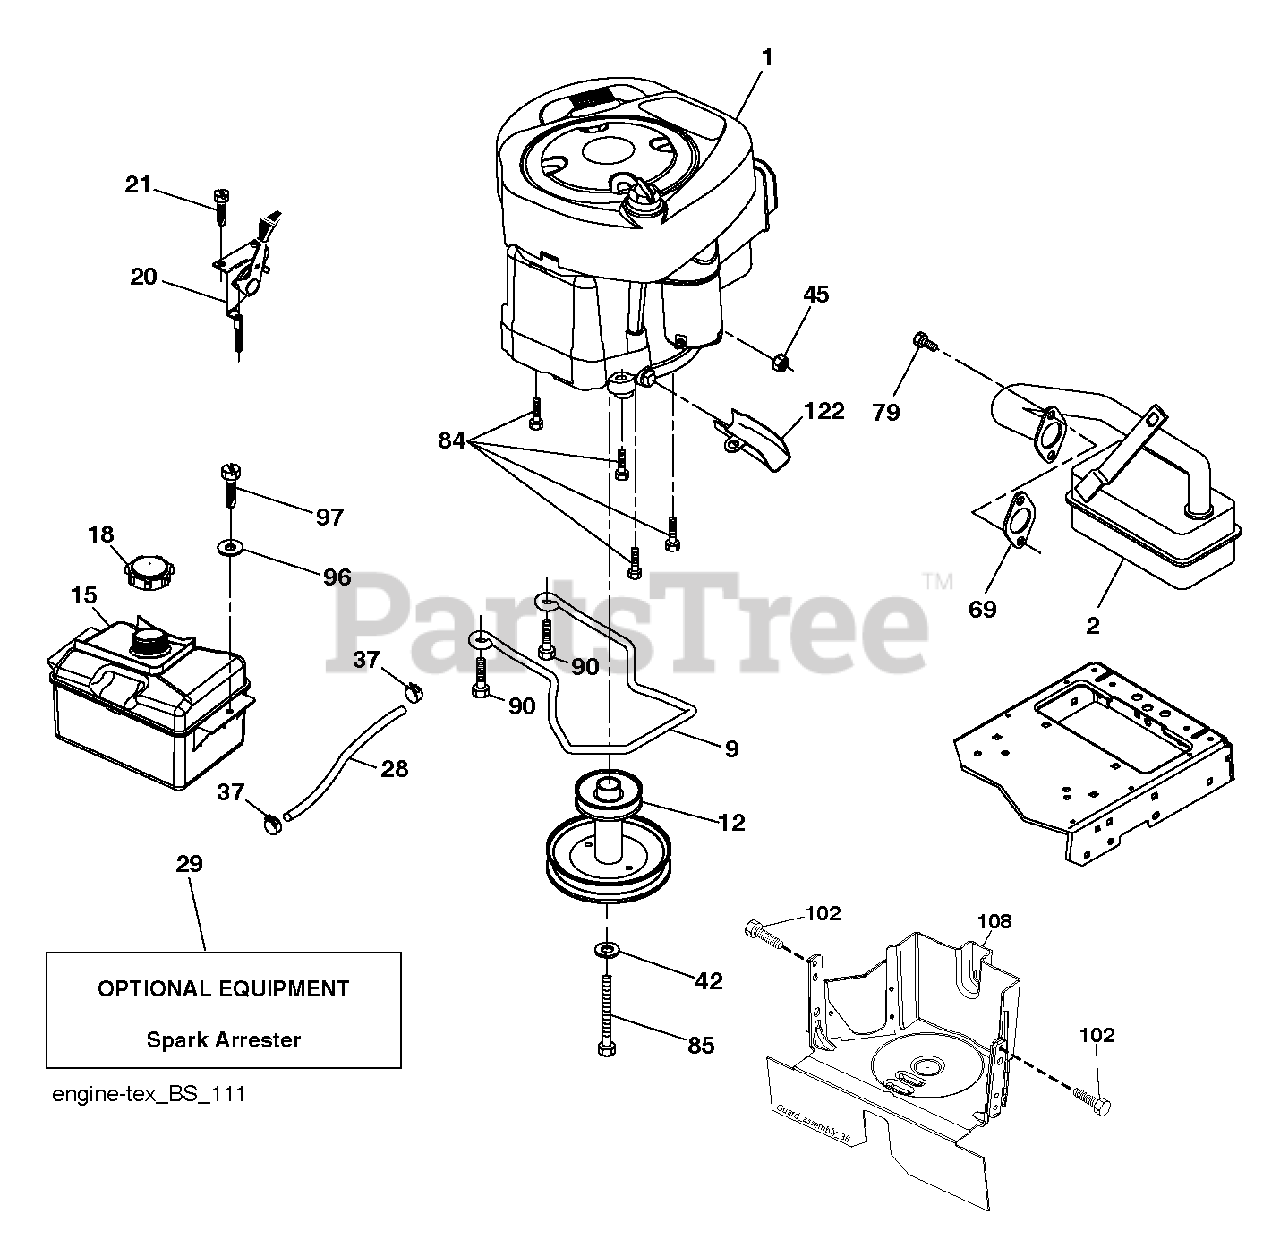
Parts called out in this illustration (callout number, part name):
2	MUFFLER.B&S.MODEL.21.11HP.OHV
9	KEEPER.BELT.ENG.3.25"2BOLT.PNT
12	PULLEY.ENG.CL.MECH.SLVR.LT/YT
15	FUEL.TANK.ASM.NON-EPA
18	CAP ASM.FUEL.2.25"FR.
20	THROTTLE.COBRA.21".RSTART.BLK
21	SCREW.#10 X 0.750.BOS
28	LINE.FUEL.20
29	KIT.SPARK ARRESTOR 794945 B&S
37	HOSE CLAMP
42	WASHER 7/16 LOCK
45	NUT
69	REPL BY 532 27 22-93
79	SCREW.SOCKET HD.5/16-1
84	SCREW.3/8-16
85	BOLT.HEX.7/16-20X4.GR5.1.5BLUE
90	SCREW 3/8-16X1
97	SCREW HEXWSHR 1/4-20X3/4
102	SCREW
108	COVER.PULLEY.ENGINE.W
122	EXTENSION DRAIN OIL
